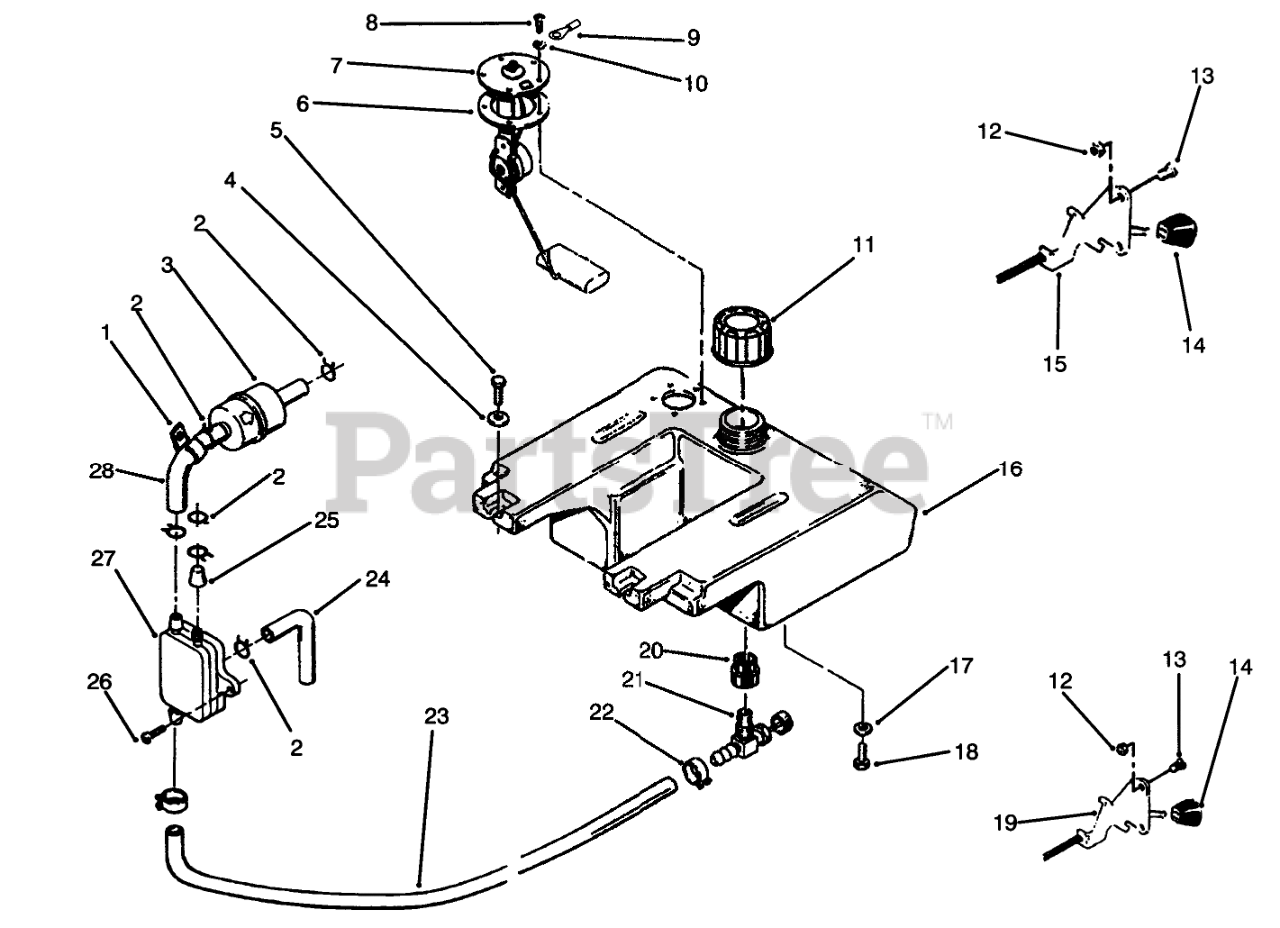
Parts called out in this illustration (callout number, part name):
1	Clip
2	CLAMP-HOSE
3	FILTER-FUEL
4	WASHER-FLAT
5	SCREW-HWHTF
6	GASKET-SENDER, FUEL
7	SENDER-FUEL LEVEL
8	Screw
9	TERMINAL-GROUND
10	WASHER-LOCK
11	GAS CAP ASM
12	Nut
13	Screw
15	CONTROL-THROTTLE
16	Tank-Fuel (Incl. Ref. #20-21)
17	WASHER-LOCK
18	SCREW-HH
19	CONTROL-CHOKE
20	BUSHING
21	VALVE-FUEL
22	CLAMP-HOSE
23	FUEL HOSE 75" OF 6554
24	Hose
25	CAP-FUEL OUTLET
26	SCREW-TAPPING PAN HD
27	PUMP-FUEL
28	FUEL HOSE
